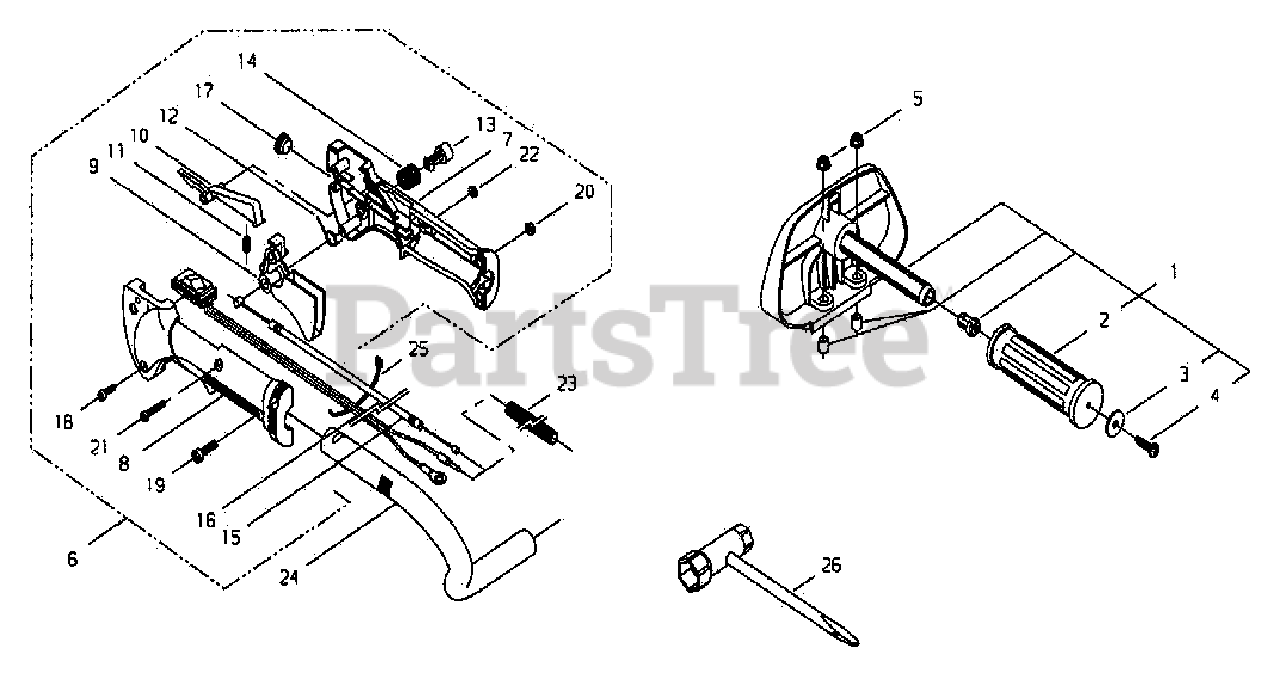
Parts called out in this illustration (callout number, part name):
1	HANDLE ASSY - FRONT
2	HANDLE - FRONT
3	WASHER - 5
4	SCREW - 5X20
5	NUT - 5
6	HANDLE ASSY - REAR
7	GRIP BODY - RIGHT
8	HANDLE, CONTROL - LEFT
9	TRIGGER, THROTTLE
10	LEVER, TRIGGER LOCKOUT
11	SPRING
12	SPRING
13	BUTTON, THROTTLE LOCK
14	SPRING
15	CABLE, THROTTLE
16	IGNITION SWITCH ASSY
17	PLUG
18	SCREW - 4X16 -- TAPPING
19	SCREW - 5X20
20	NUT - 5
21	SCREW - 4X23
22	NUT - 4
23	TUBE, PROTECTIVE - PLASTIC
24	HANDLE - REAR
25	TIE, CABLE
26	T-WRENCH - 13X16mm
